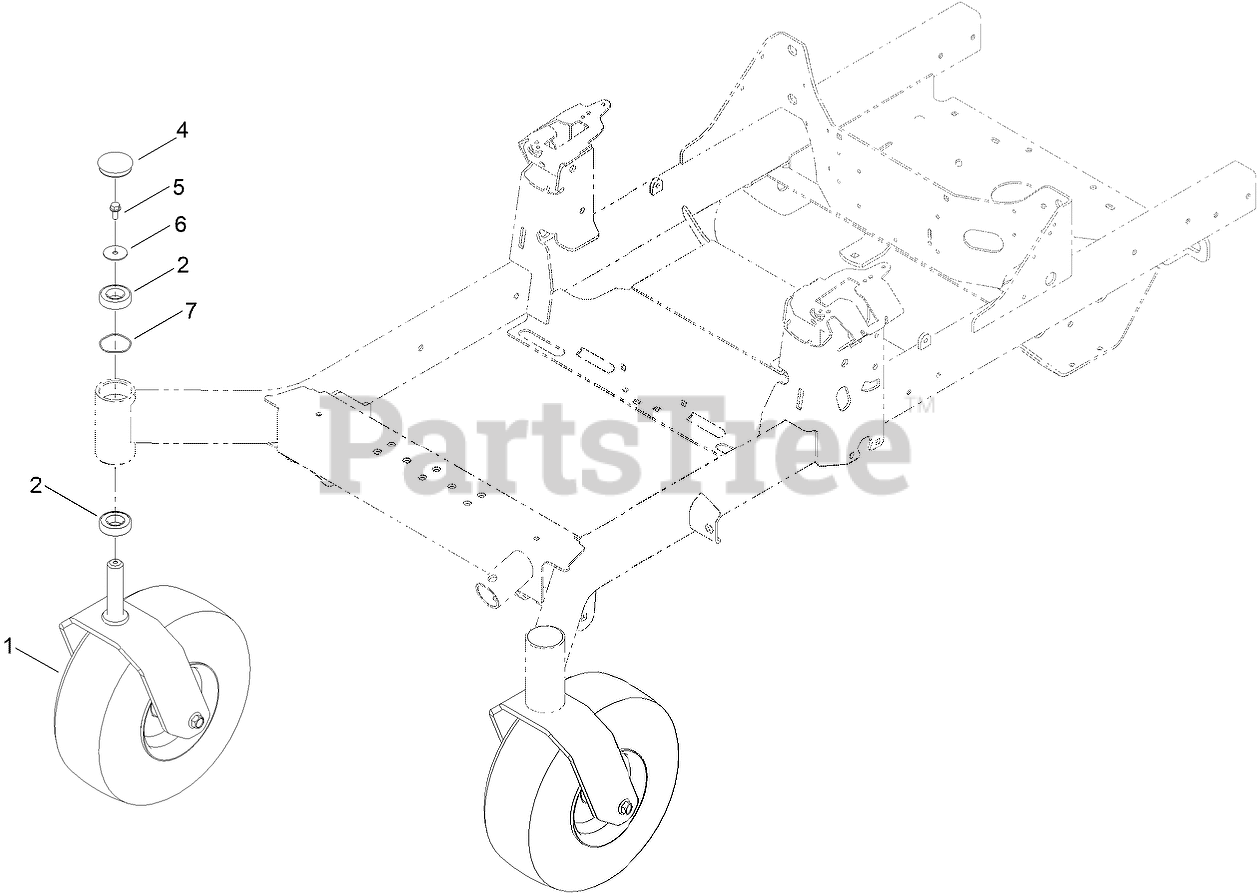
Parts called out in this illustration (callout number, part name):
1	ASM-FRONT CASTER W/FORK [BB-BLACK]
2	BEARING-BALL
4	CAP,GREASE
5	SCREW-HHF
6	WASHER-FLAT
7	SPACER-BEARING
